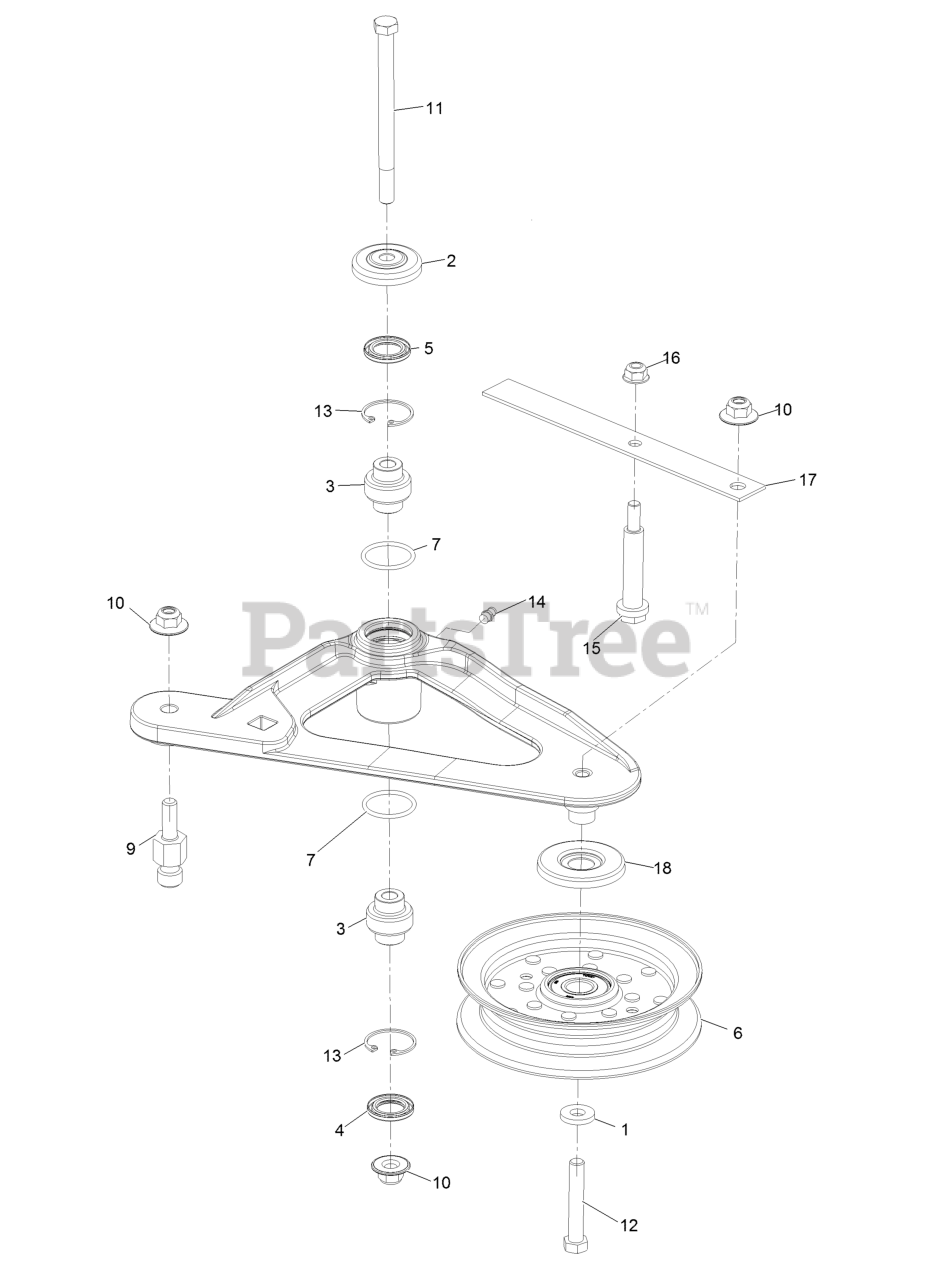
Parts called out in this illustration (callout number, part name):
2	Guard-Top
3	Bearing-Spherical
4	Seal-Lip, Double
5	Seal-Single Lip
6	Idler-Pulley, Flat
9	Pin-Spring, Anchor
10	Nut-Nyloc 3/8-16 Flg
11	Screw-Shoulder 3/8-16 X 5
12	Screw-HH
13	Ring-Retaining
14	Zerk-1/4-28 Str
15	Screw-Shoulder 5/16-18 X 1 29/32
16	Nut-Nyloc 5/16-18 Flg
17	Spring-Belt
18	Shield-Guard, Dust
